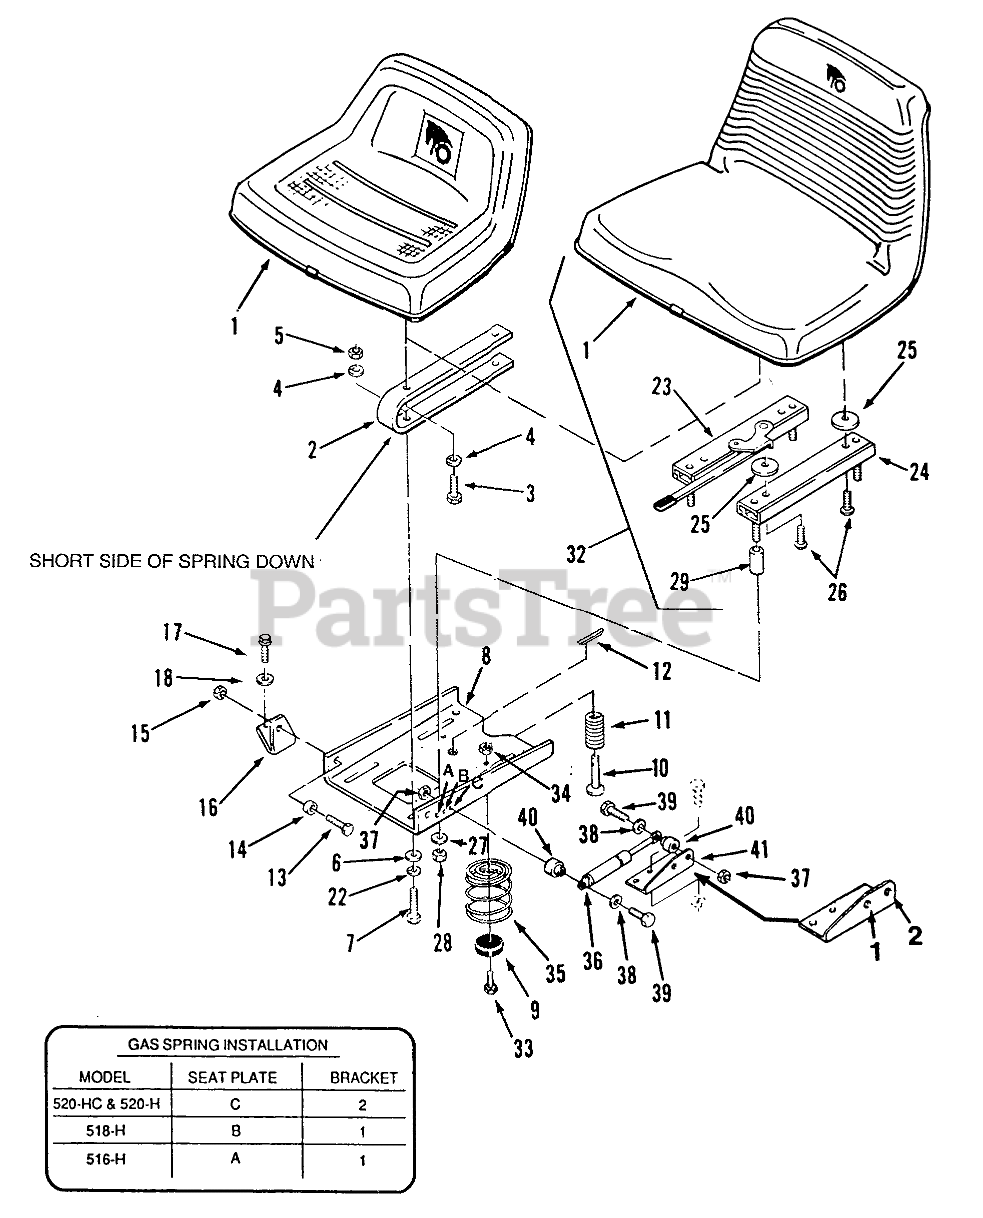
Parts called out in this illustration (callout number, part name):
1	Seat
2	Seat Spring
3	Bolt
4	Lockwasher
5	Nut
6	WASHER 5/16 SAE
7	HHCS
8	PLATE-SEAT PIVOT B
9	BUMPER
11	SPRING-SEAT SWITCH
12	Cotter Pin
13	HHCS
14	BUSHING
15	Nut
16	Bracket-Pivot RH
17	Bolt
23	Adjuster-Seat
24	ADJUSTER-R.H. SEAT
25	SPACER-NYLON
26	Screw
27	Collar
28	Nut
29	SPACER
33	Bolt
34	Nut
35	SPRING
36	GAS SPRING
37	Nut
39	Bolt
40	SPACER
41	BRACKET-CYLINDER R
